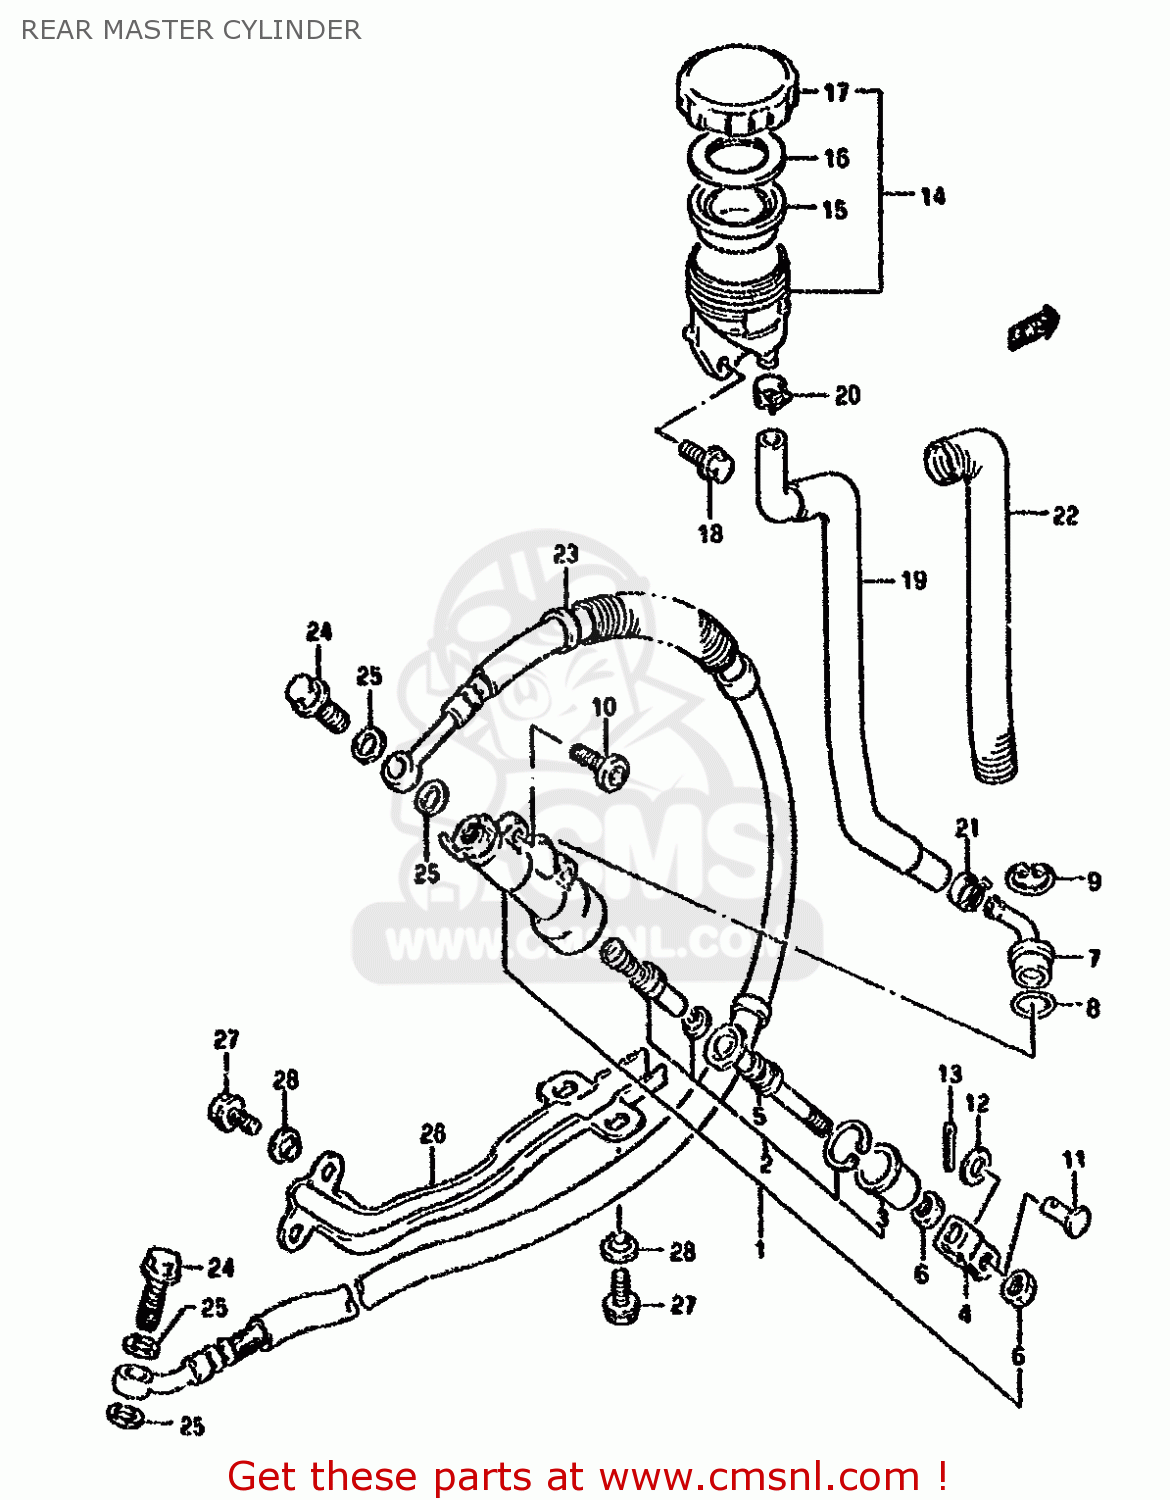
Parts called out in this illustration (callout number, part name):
1	CYLINDER ASSY, REAR MASTER
2	PISTON/CUP SET
3	BOOT
4	YOKE
5	ROD,PUSH
6	NUT
7	CONNECTOR
8	O RING
9	CIRCLIP
10	BOLT(6X18)
11	PIN(8X20)
12	WASHER(8.5X13X1.6)
13	PIN
14	TANK ASSY,RR RESERVOIR
15	DIAPHRAGM
16	PLATE,DIAPHRAGM
17	CAP
18	BOLT
19	HOSE,RESERVOIR TANK
20	CLIP
21	CLIP
22	SHIELD, HOSE HEAT
23	HOSE,RR BRAKE
24	BOLT UNION
25	WASHER(10X15X1.5)
26	PROTECTOR, BRAKE HOSE
27	BOLT 6X12
28	WASHER
